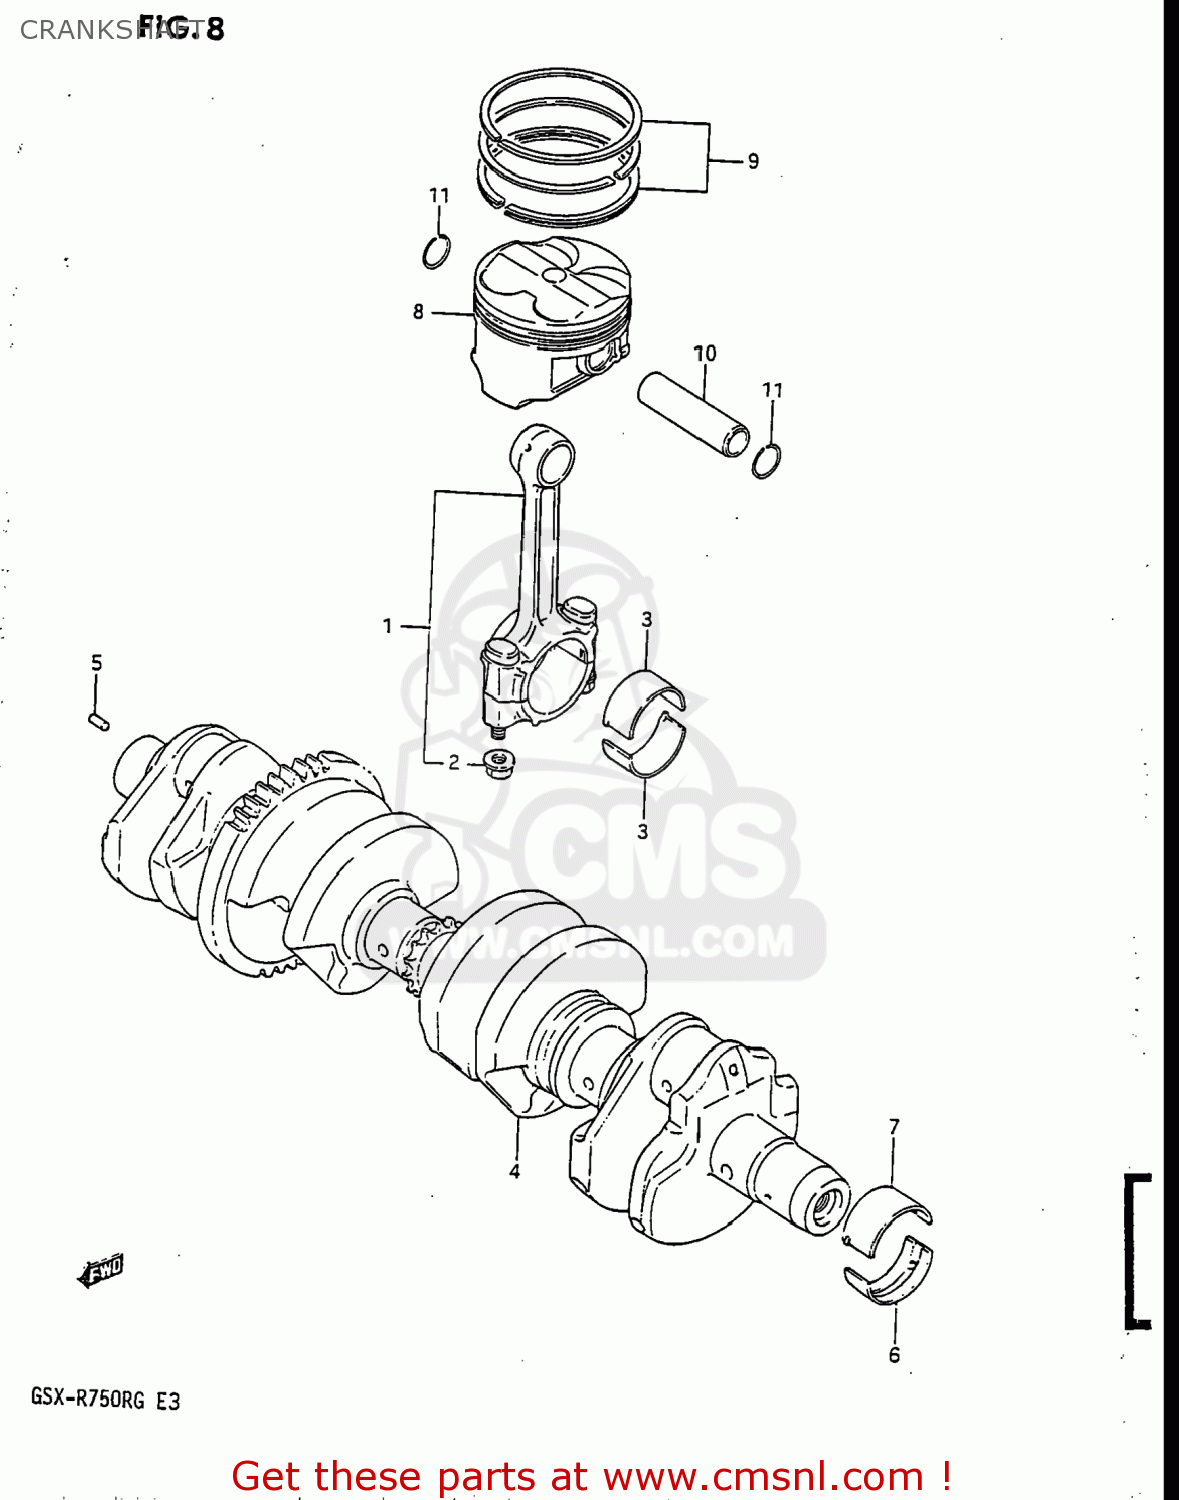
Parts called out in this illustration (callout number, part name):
1	ROD ASSEMBLY,CONNECTING
2	NUT
3	BEARING,CRANK PIN
4	CRANKSHAFT
5	PIN
6	BEARING,CRANKSHAFT LWR
7	BEARING,CRANKSHAFT UPR
8	PISTON
9	RING SET,PISTON
10	PIN,PISTON
11	CIRCLIP
